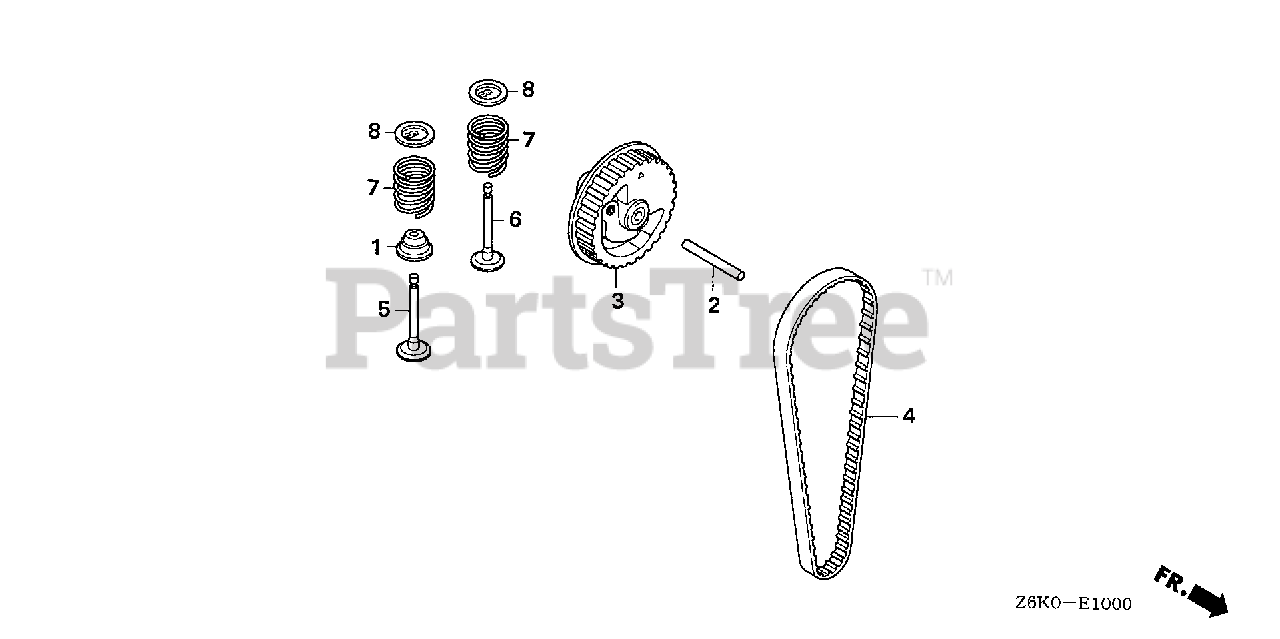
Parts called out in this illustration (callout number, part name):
1	SEAL, VALVE STEM
2	ROLLER (4X31.8)
3	PULLEY, CAMSHAFT
4	BELT, TIMING (76ZU6 G-310)
4	BELT, TIMING (76ZU5 G-310)
5	VALVE, IN. (ZI)
5	VALVE, IN. (FI)
6	VALVE, EX. (ZE)
6	VALVE, EX. (FE)
7	SPRING, VALVE
8	RETAINER, VALVE SPRING
